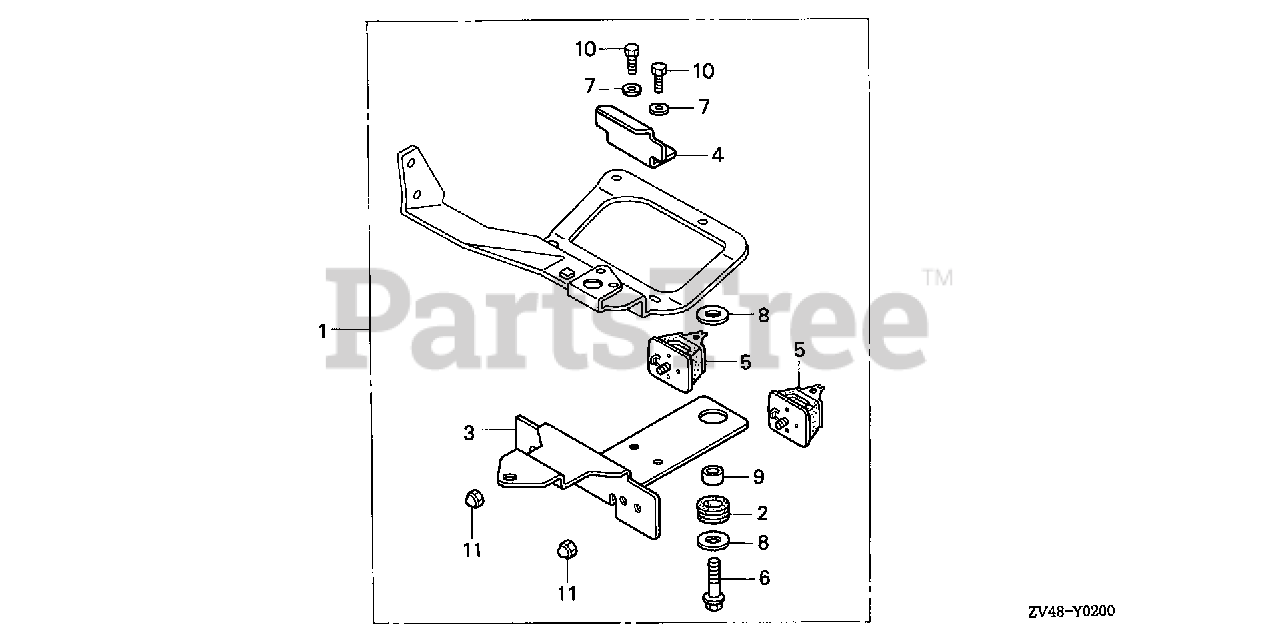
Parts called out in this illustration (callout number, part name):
1	BRACKET KIT, REMOTE CONTROL (NOT AVAILABLE)
2	RUBBER, BATTERY BOX MOUNTING
3	PLATE, STEERING
4	PLATE, BRACKET STOP
5	RUBBER, MOUNTING
6	BOLT, FLANGE (8X40)
7	WASHER, PLAIN (6MM)
8	WASHER, PLAIN (8MM)
9	COLLAR, STEERING
10	BOLT, HEX. (6X16)
11	NUT, CAP (6MM)
